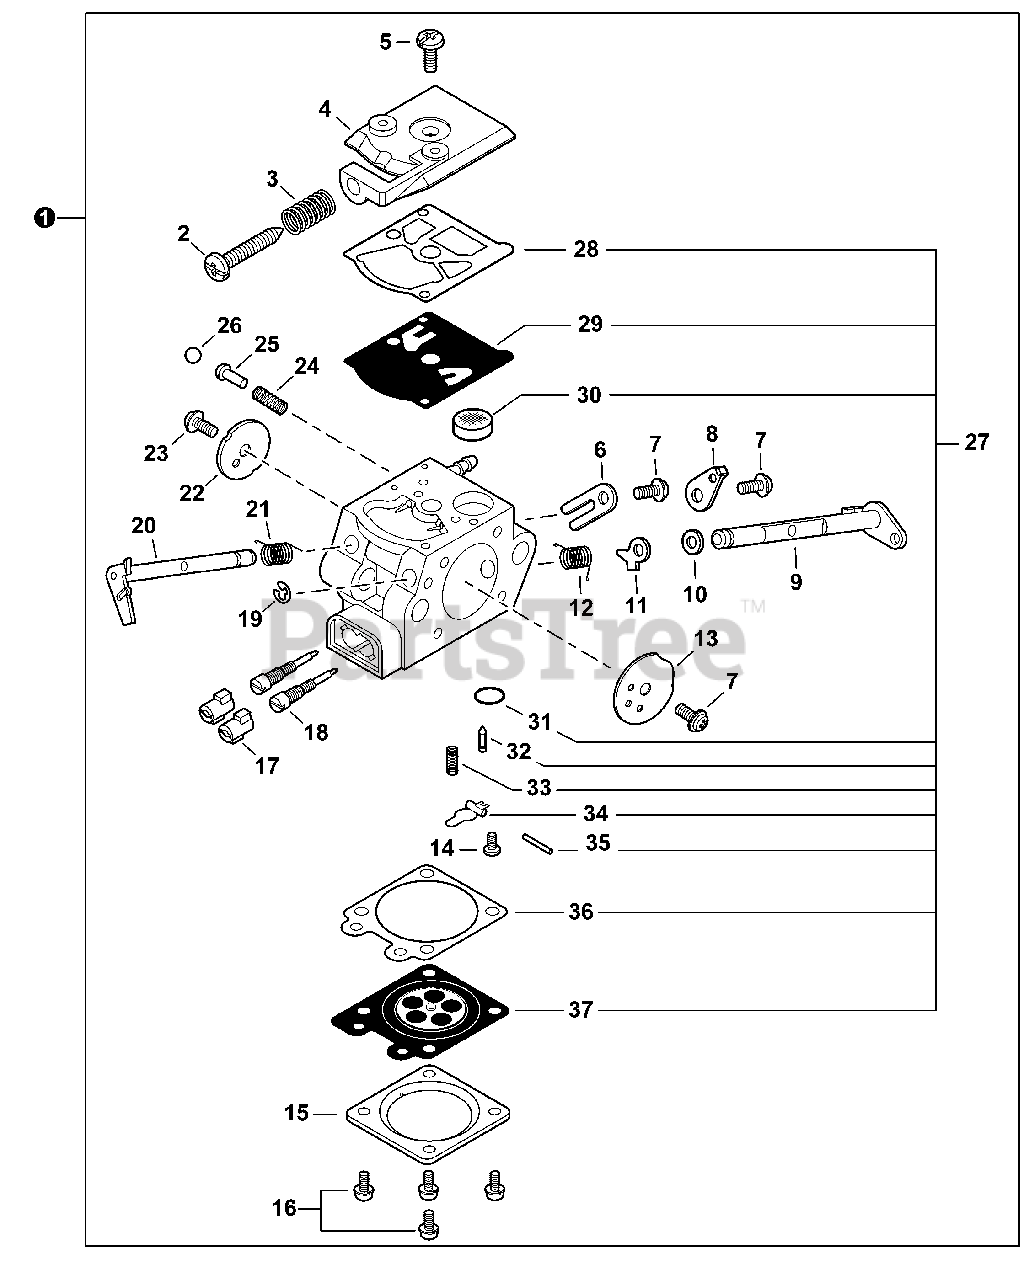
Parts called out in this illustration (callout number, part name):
1	CARBURETOR - WT-992
2	SCREW, IDLE ADJUST
3	SPRING, IDLE ADJUST
4	COVER, PUMP
6	CLIP, THROTTLE SHAFT
8	LEVER, THROTTLE
9	SHAFT, CHOKE
11	LEVER, FAST IDLE
13	VALVE, CHOKE
14	SCREW, METERING LEVER PIN
15	COVER, METERING DIAPHRAGM
17	CAP, LIMITER
18	NEEDLE, MIXTURE
20	SHAFT ASSY, THROTTLE
21	SPRING, THROTTLE RETURN
22	VALVE, THROTTLE
24	SPRING, START VALVE
25	PISTON ASSY
27	REPAIR KIT, CARBURETOR
28	GASKET, PUMP
29	DIAPHRAGM, PUMP
30	SCREEN, FUEL INLET
31	PLUG, WELCH
32	VALVE, INLET NEEDLE
33	SPRING, METERING LEVER
34	LEVER, METERING
35	PIN, METERING LEVER
36	GASKET, METERING DIAPHRAGM
37	DIAPHRAGM, METERING
